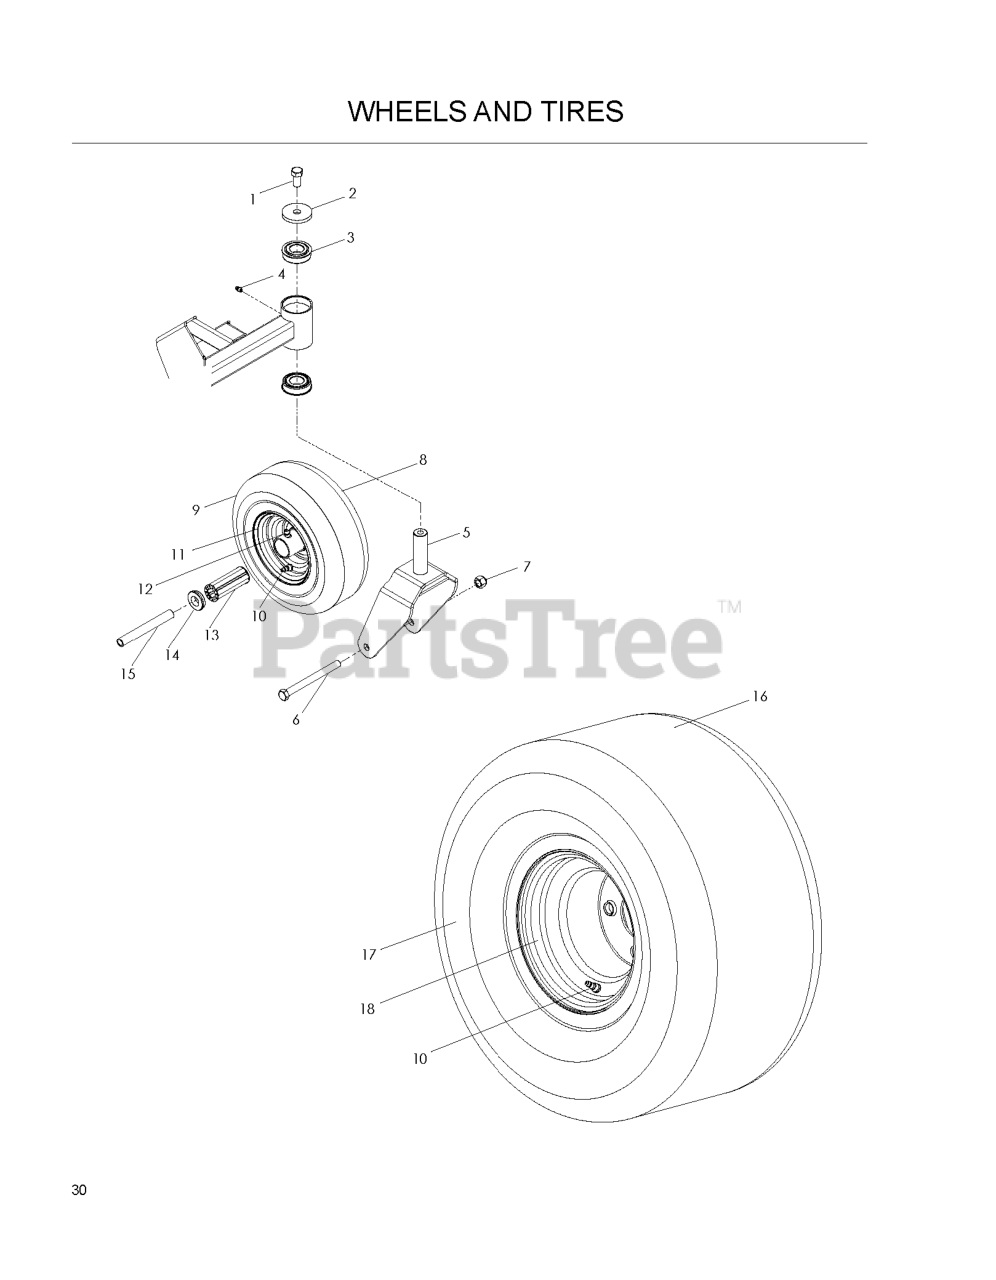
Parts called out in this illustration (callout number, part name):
1	HHCS 1/2-13 X 1
2	HEAVY WASHER
3	BEARING FLANGED
5	CASTER YOKE - PAINTED
6	HCS 1/2C X 5 1/2
7	NUT 1/2-13 HEX NYLOC ZD
8	TIRE/WHEEL.CASTER
9	TIRE - CASTER
10	VALVE STEM TR-412
12	ZERK
13	ROLLER BEARING-CAGED 3 1/4'
14	BEARING RETAINER
16	TIRE ASM, 20 X 8-8
16	TIRE ASM, 20X10-.8 NEG SILVER
16	TIRE/WHEEL ASM 18X9.5-8
16	TIRE ASM 18 X 8.5-8
17	TIRE 20 X 8, TURF
17	TIRE, 18 X 8.5, TURF RIDER
17	TIRE, 20 X 10-8
17	TIRE, 18 X 9.5 - 8
18	RIM.8X7.SILVER.ZTR
18	RIM.8X7.W/8".OFFSET.SILVER.ZTR
